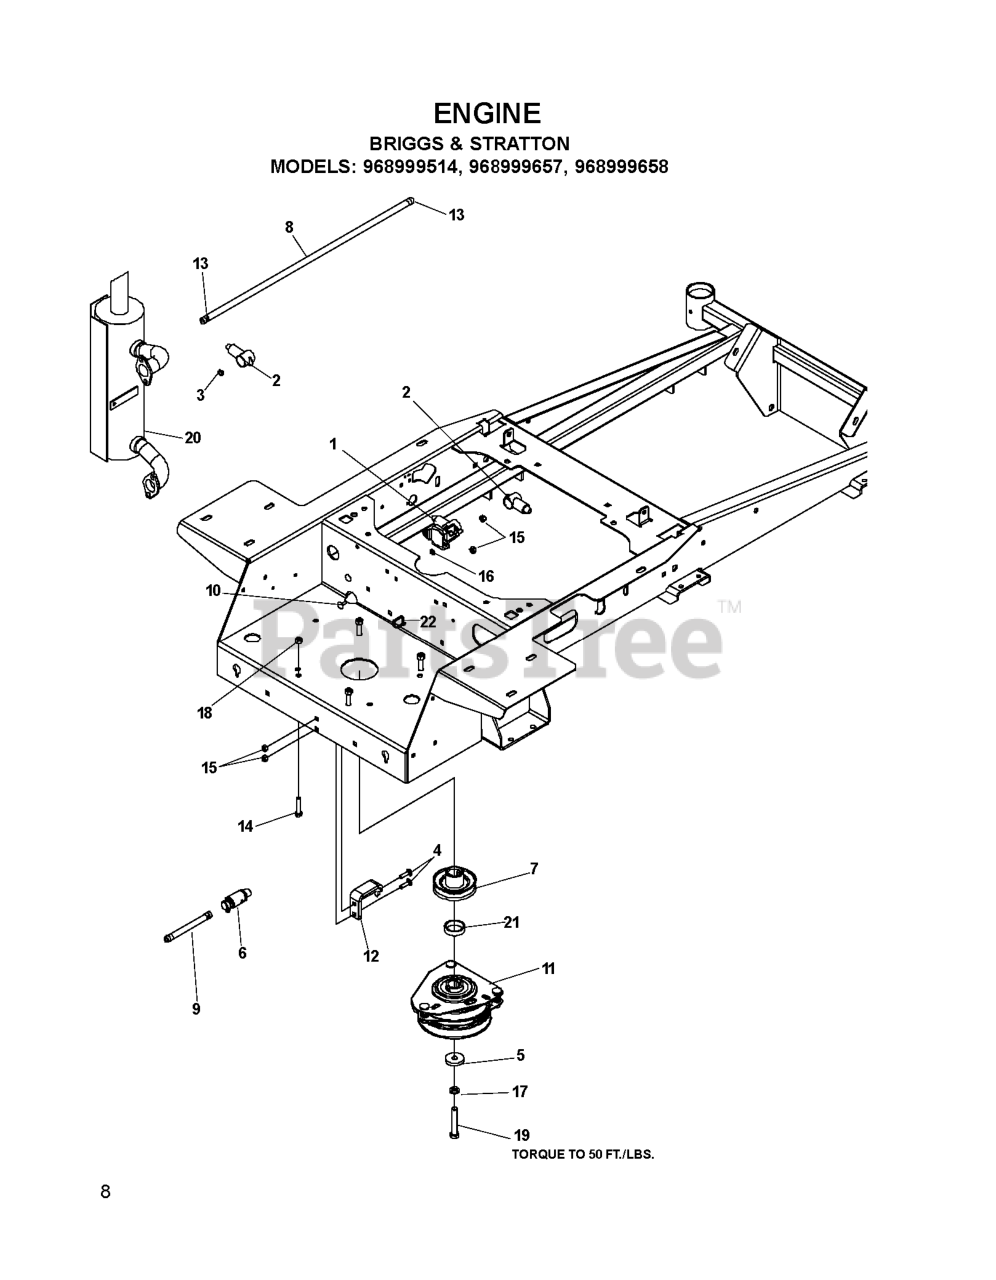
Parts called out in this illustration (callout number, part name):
3	JAM NUT 1/4C (2 2 PW01)
4	RHSNB, 1/4-20 X 1, GR5
5	CLUTCH, WASHER
6	OIL DRAIN FITTING
7	PULLEY, ENGINE
8	FUEL LINE 24"
9	FUEL LINE 5"
10	RHSSNB, 1/4-20X5/8
11	CLUTCH, OGURA - 90 FT/LB
12	CLUTCH TIE DOWN
13	HOSE CLAMP
14	CAPSCREW 5/16 X 1/1/2 HEX HEAD
15	NUT.1/4-20.HEX.NYLOC.ZD
16	WASHER 1/4 INT TOOTH
17	WASHER 7/16 LOCK
18	NUT 5/16 NYLOC
19	BOLT 7/16F X 2 1/2
21	SPACER, ENGINE, PULLEY
22	TIE, PLASTIC
